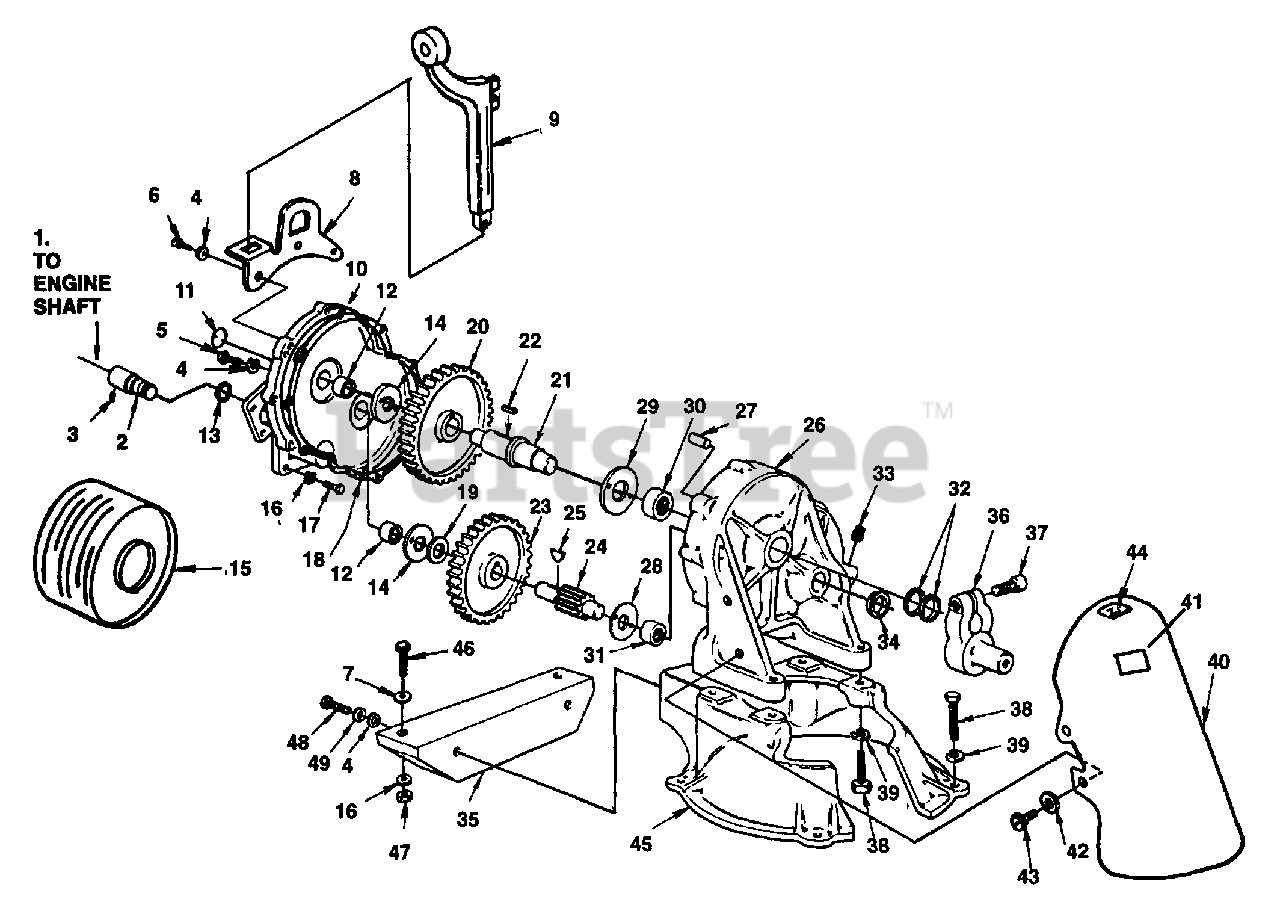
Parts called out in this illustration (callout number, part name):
2	SHAFT - Extension
3	SCREW - set 1/4-20 x 3/8
4	WASHER - lock, 1/4
5	SCREW - hex hd., 1/4-20 x 1
6	SCREW - hex hd., 1/4-20 x 1 1/4
7	WASHER, flat - 5/16
8	BRACKET, lifting
9	WRENCH-Spanner
10	GEAR CASE COVER
11	CAP, bearing
12	BEARING, Needle
13	SEAL, extension shaft
14	WASHER, thrust
15	STRAINER
16	WASHER, lock 5/16
17	SCREW, hex hd., 5/16-24 x 7/8
18	GASKET, gear case
20	GEAR, pump
21	SHAFT, gear
23	GEAR, intermediate
24	SHAFT - pinion
26	GEAR CASE ASSEMBLY
27	PIN, dowel
28	WASHER, thrust
29	WASHER, thrust
30	BEARING, needle
31	BEARING, needle
32	SEAL - Garlock
33	PLUG, pipe
34	CAP - Bearing
35	BRACKET, engine to pump
37	SCREW, socket hd., 1/2-13 x 1 1/2
38	SCREW, hex hd., 1/2-13 x 1 3/4
39	WASHER, lock 1/2
40	GUARD, pump rod
41	GREASE DECAL
42	WASHER, flat
43	SCREW, hex hd., 12-24 x 3/8
44	WARNING DECAL
45	BODY, pump (upper)
46	SCREW, hex hd., 5/16-18 x 1 3/4
47	NUT, hex 5/16-18
48	SCREW, hex hd. 1/4-20 x 3/4
49	WASHER, Flat 1/4
